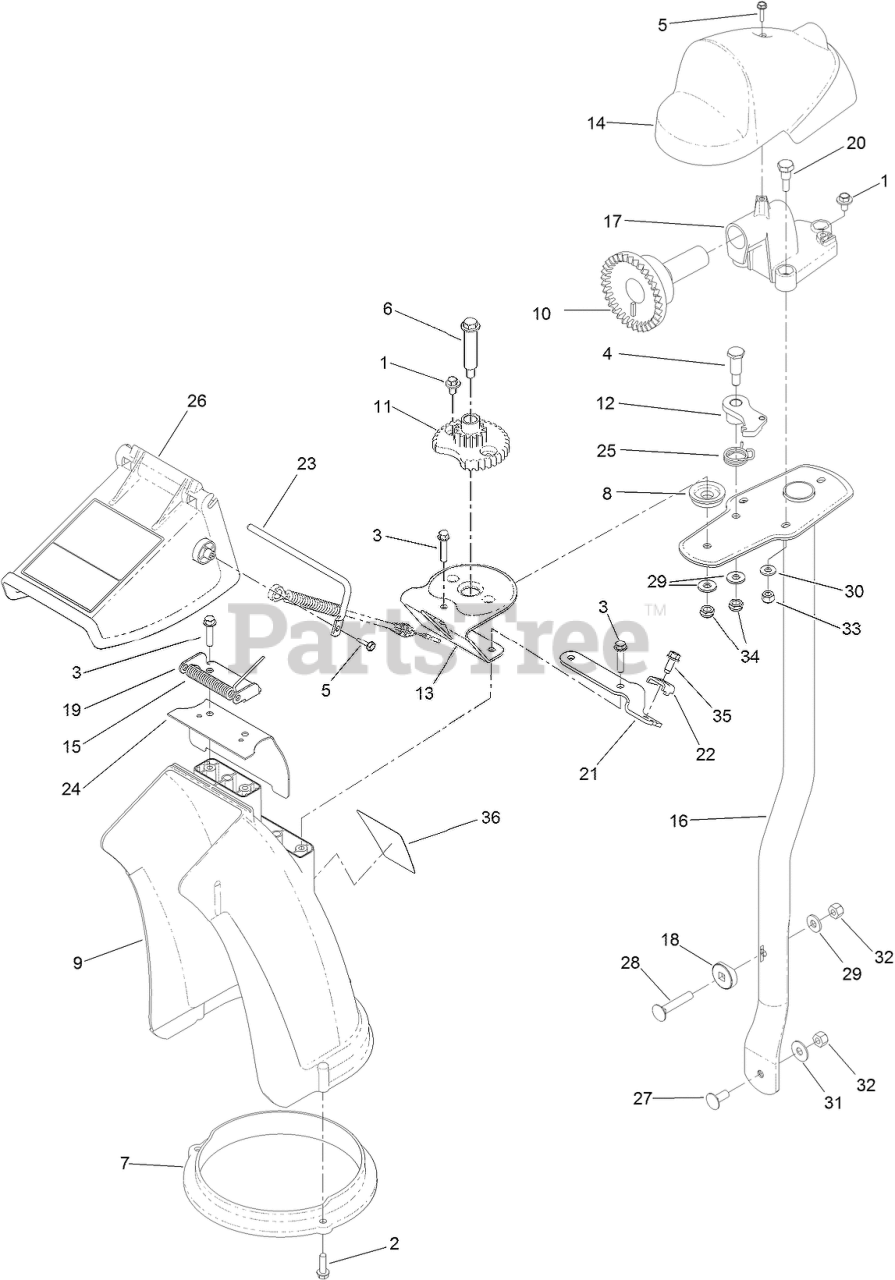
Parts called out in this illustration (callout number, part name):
1	SCREW AND WASHER ASM
2	SCREW-HWH
3	SCREW-PLASTITE
4	SCREW-SHOULDER
5	SCREW-HWH
6	BOLT-SHOULDER
7	RING-CHUTE
8	SPACER-CHUTE
9	CHUTE-DISCHARGE
10	GEAR-FACE
11	GEAR-CHUTE
12	LATCH-CHUTE
13	BRACKET-SUPPORT, CHUTE
14	COVER-GEAR, CHUTE
15	SPRING-TORSION
16	TUBE-SUPPORT
17	MOUNT-GEAR, FACE
18	WASHER-CURVED
19	BRACKET-DEFLECTOR
20	SCREW-SHOULDER
21	BRACKET-CLAMP, CABLE
22	CLAMP-CABLE
23	ROD-DEFLECTOR
24	SEAL-CHUTE
25	SPRING-TORSION
26	DEFLECTOR-CHUTE, CE
27	SCREW-CARR
28	SCREW-CARR
29	WASHER-FLAT
30	WASHER-FLAT
31	WASHER-BELLEVILLE
32	NUT-LOCK, NI
33	NUT-LOCK, NI
34	NUT-LOCK, NI
35	SCREW-HWH
36	DECAL-GUARANTEE
